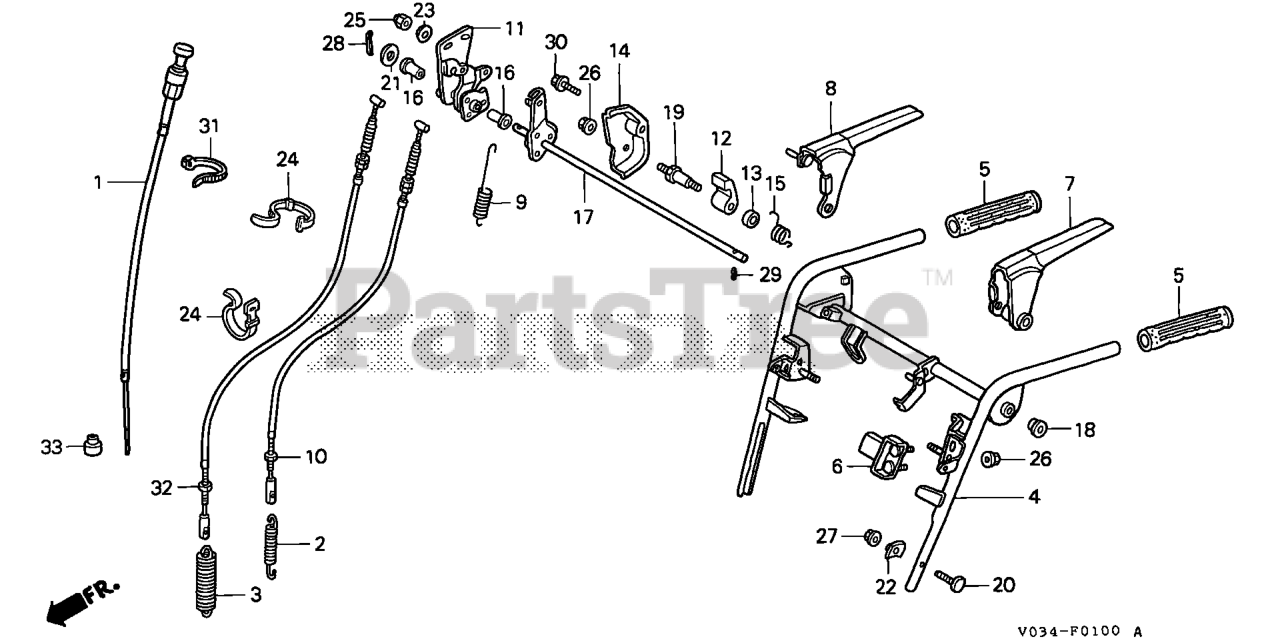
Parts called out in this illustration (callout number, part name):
1	CABLE, CHOKE
2	SPRING, TENSIONER ROLLER
3	SPRING, TENSIONER ROLLER (AUGER)
4	PIPE, HANDLE (UPPER)
5	GRIP, HANDLE
6	STOPPER, CHANGE LEVER
7	LEVER, CLUTCH
8	LEVER, AUGER CLUTCH
9	SPRING, CLUTCH LEVER
10	CABLE, CLUTCH
11	BOSS, CAM LOCK
12	RATCHET, LEVER
13	COLLAR, RATCHET
14	COVER, RATCHET
15	SPRING, RATCHET
16	BUSH (13X22.5) (GRAY)
17	SHAFT, CLUTCH LEVER
18	BUSH (14MM)
19	BOLT, PIVOT (6MM)
20	BOLT, HANDLE HOLDER
21	WASHER (10MM)
21	WASHER, THRUST (10MM)
22	WASHER, FRAME JOINT
23	WASHER (6MM)
24	BAND, WIRE (95MM)
25	NUT, CAP (6MM)
26	NUT, FLANGE (6MM)
27	NUT, FLANGE (8MM)
28	PIN, COTTER (3.0X18)
29	PIN, SPRING (4X16)
30	BOLT, FLANGE (6X10)
31	BAND, WIRE (165MM) (BLACK)
32	CABLE, AUGER CLUTCH
33	CAP, CABLE
